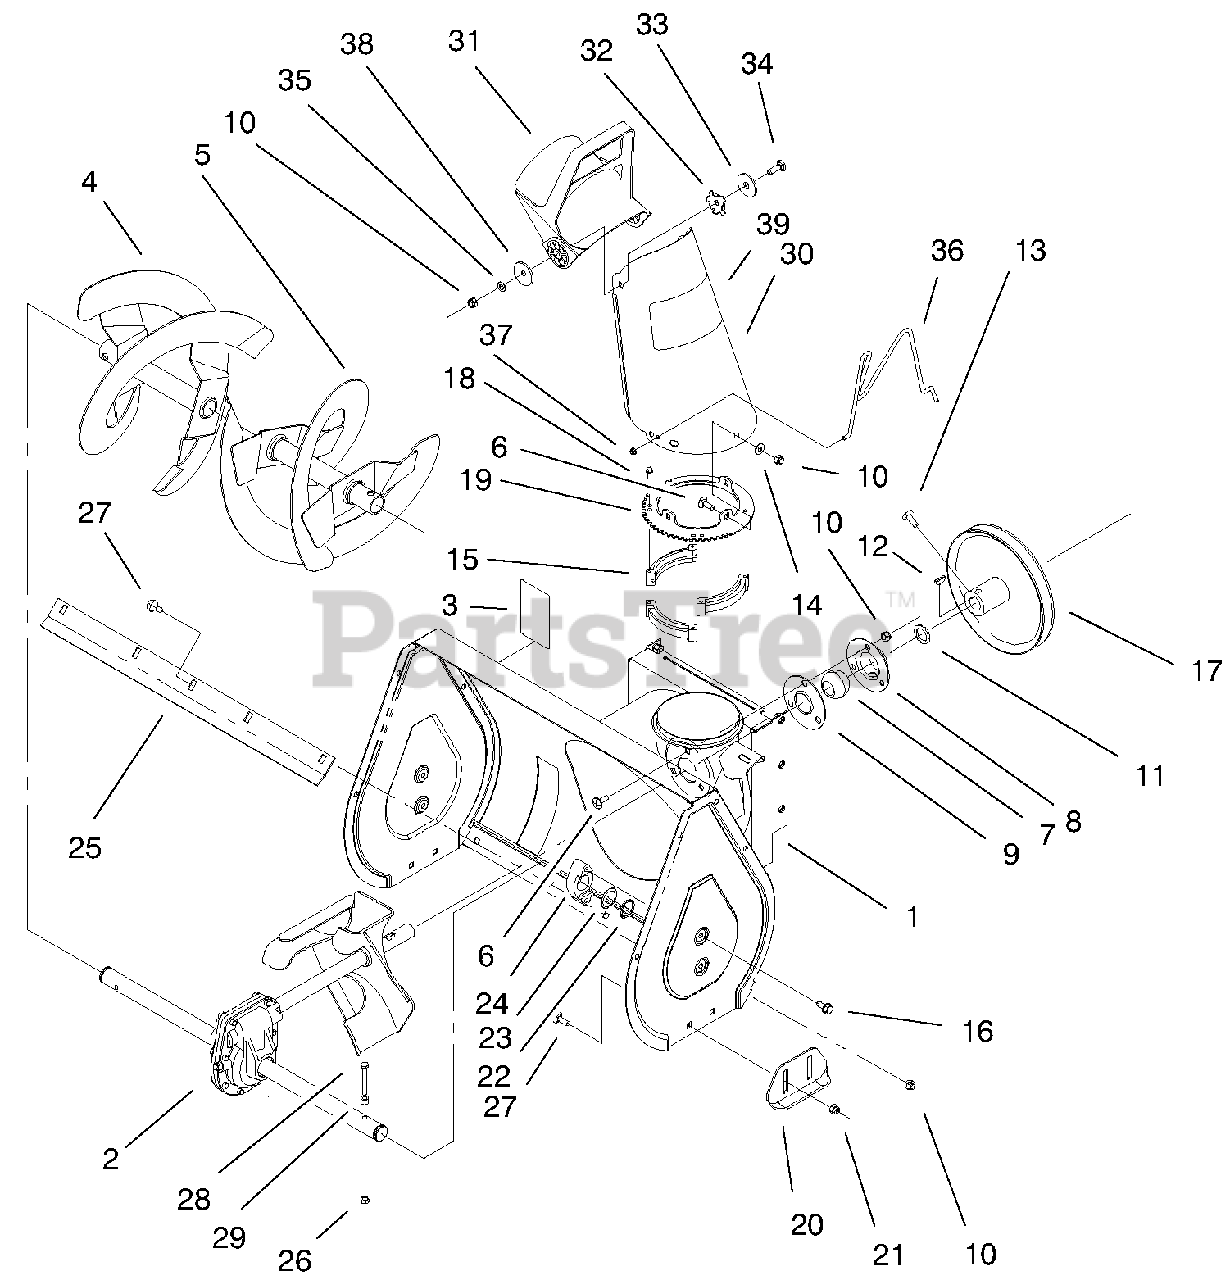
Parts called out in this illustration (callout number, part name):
1	Auger Hsg ASM
2	Gear Case ASM
3	Decal-Warning, Auger
4	Auger Wa RH
5	Auger Wa LH
6	Carriage Bolt
7	Bearing-Ball
8	Flange-Cup, Bearing
9	Flange-Cup, Bearing
10	Nut-Lock
12	Key-Woodruff
13	Screw-SQH
14	Washer-Flat
15	Chute Ring Retainer
17	Pulley-Impeller
18	Spec Screw
19	Chute Ring
21	Nut-Hex, Flange
22	Retaining Ring
23	Check Washer
24	Auger Bearing
25	Scraper Blade
26	Nut-Lock
27	Screw-CARR
28	Capscrew
29	Spacer-Hub, Impeller
30	ASM-Chute w/Decal
31	Chute Deflector
32	Friction Plate
33	Rubber Washer
34	Bolt S.n.
35	Washer-Belleville
36	Chute Wire
38	Flat Washer
39	Decal-Danger
